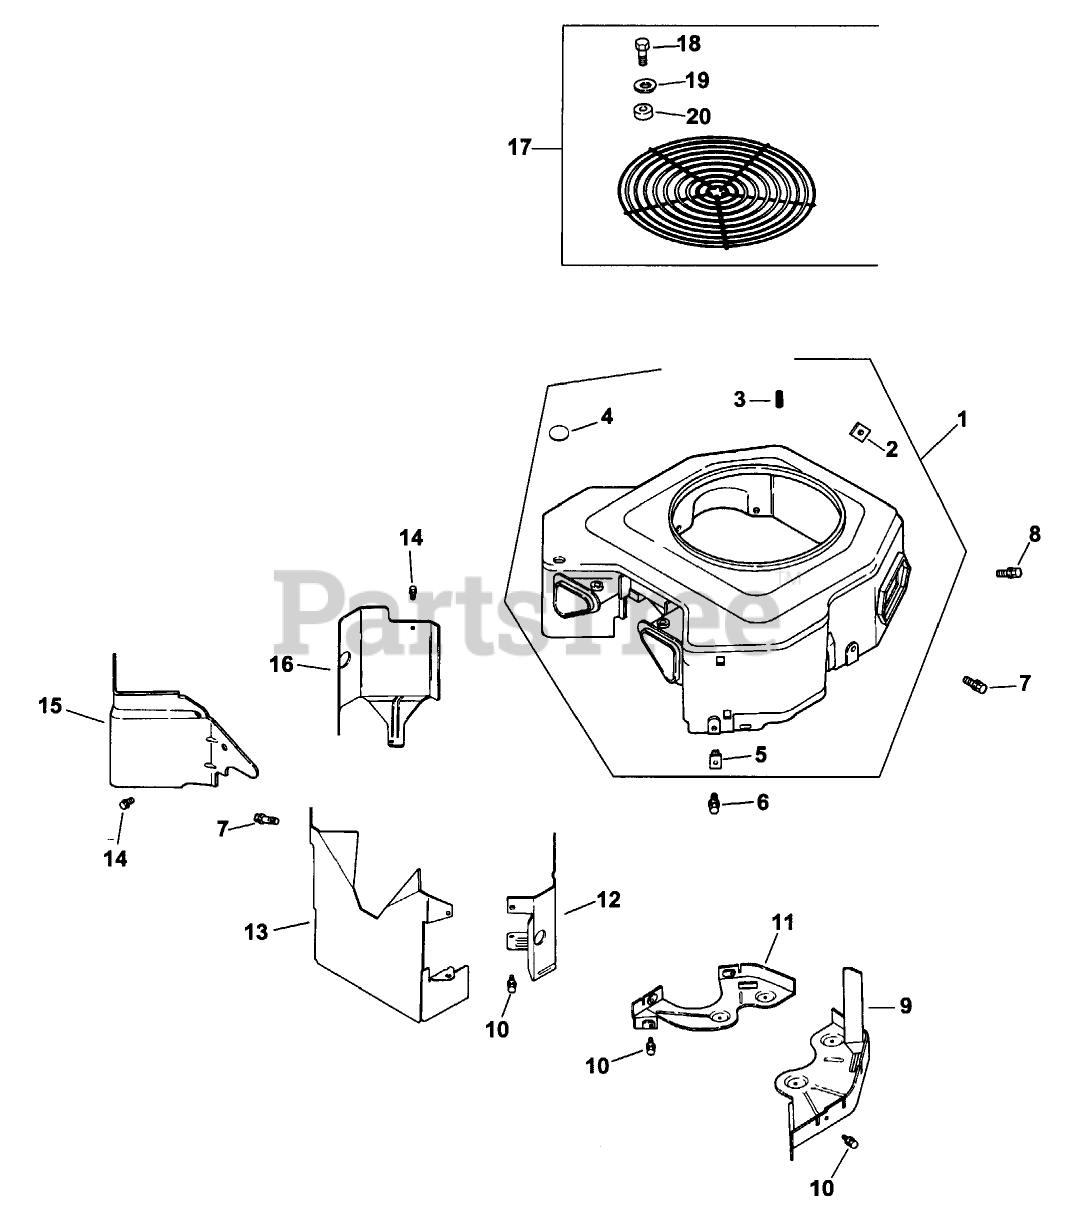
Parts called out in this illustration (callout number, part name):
1	Housing, blower (Includes 2-5)
2	Nut
3	Screw-Set
4	Plug-Button
5	Nut-Plastic
6	Screw-HF
7	Screw-HF
8	Screw
9	Plate-Backing #2 Side
10	Screw
11	Plate-Backing #1
12	Baffle-Cylinder, #2
13	Baffle-Valley #1 Side
14	Screw
15	Baffle-Valley #2 Side
16	Baffle-Cyl. #1 Side
17	Kit, guard (Includes 18-20, Threaded insert Qty. 3] 24 332 01)
18	Screw
19	Washer
20	Spacer
